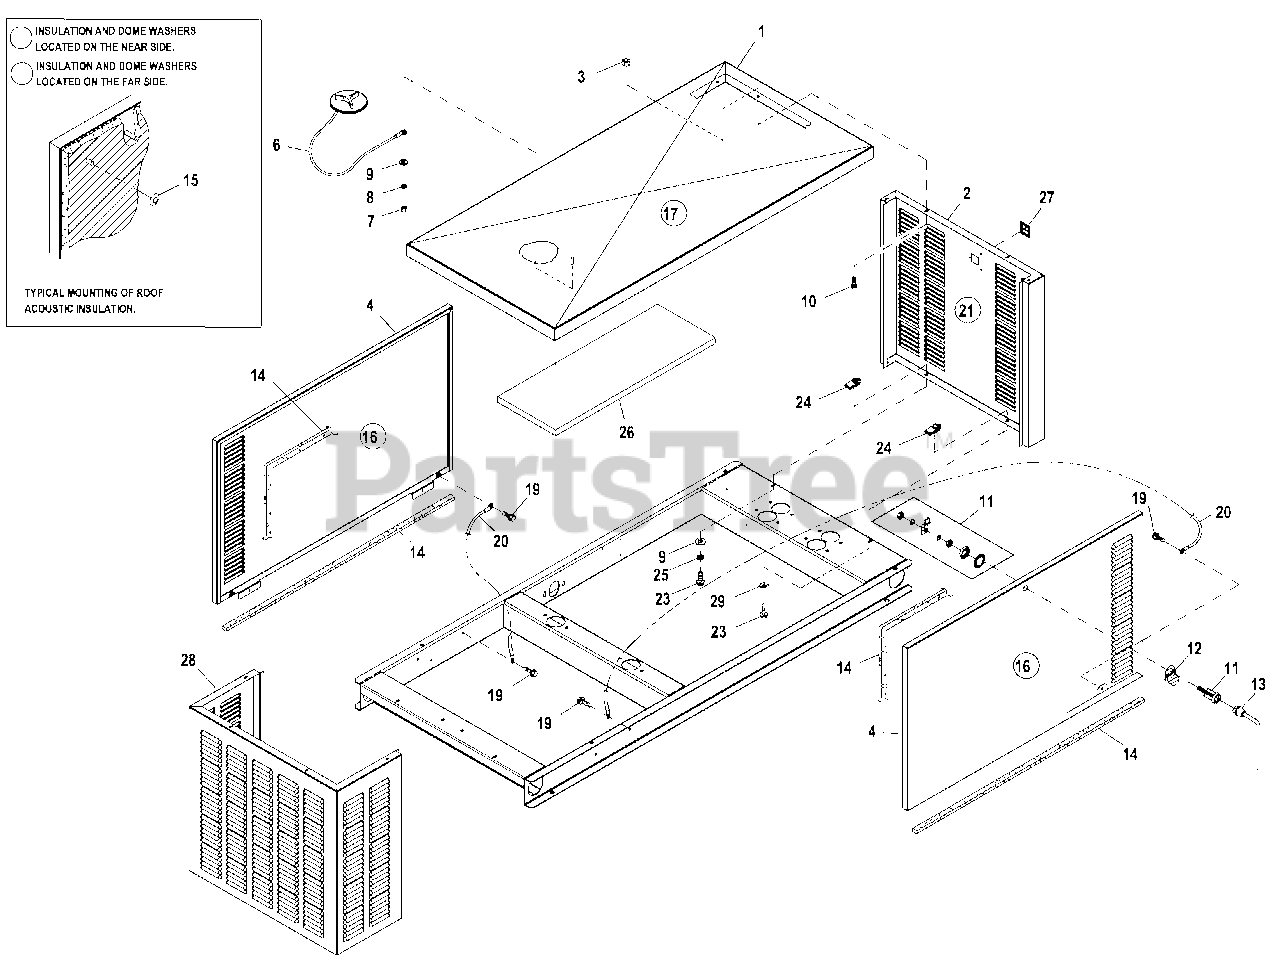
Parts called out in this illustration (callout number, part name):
1	ROOF 1.6LC1
2	REAR INTAKE WRAP C1
3	NUT HEX LOCK M6-1.0 SS NY INS
4	DOOR LEFT/RIGHT SIDE C1
6	ASSY ACCESS COVER
7	NUT HEX 1/4-20 STEEL
8	WASHER LOCK M6-1/4
9	WASHER FLAT 1/4-M6 ZINC
10	SCREW THF M6-1 X 16 N WA Z/JS
11	VISE-ACTION LATCH, SLOTTED CIR
12	TAB PULL
13	KEY VISE-ACTION LATCH,SLOT CIR
14	FOAM STRIP 3/4"WIDE X 3/16"THK (294"LG)
15	WASHER SELF LOCKING DOME
16	INSULATION SIDE DOOR C1
17	INSULATION ROOF C1
19	SCREW HWHTF M6-1.0 X 16
20	ASSY WIRE 14AWG GRN/YEL (32.25"LG)
21	INSULATION REAR C1
23	SCREW HHFC M6-1.0X 2 0 G8.8
24	NUT SPRINGCLIP M6-1.0
25	WASHER LOCK M6-1/4
26	FOIL ALUMINUM WITH ADHESIVE
27	RF COVER PLATE-PLASTIC-BISQUE
28	FRONT DISCHARGE WRAP 1.6L C1
29	WASHER LOCK SPECIAL 1/4"
